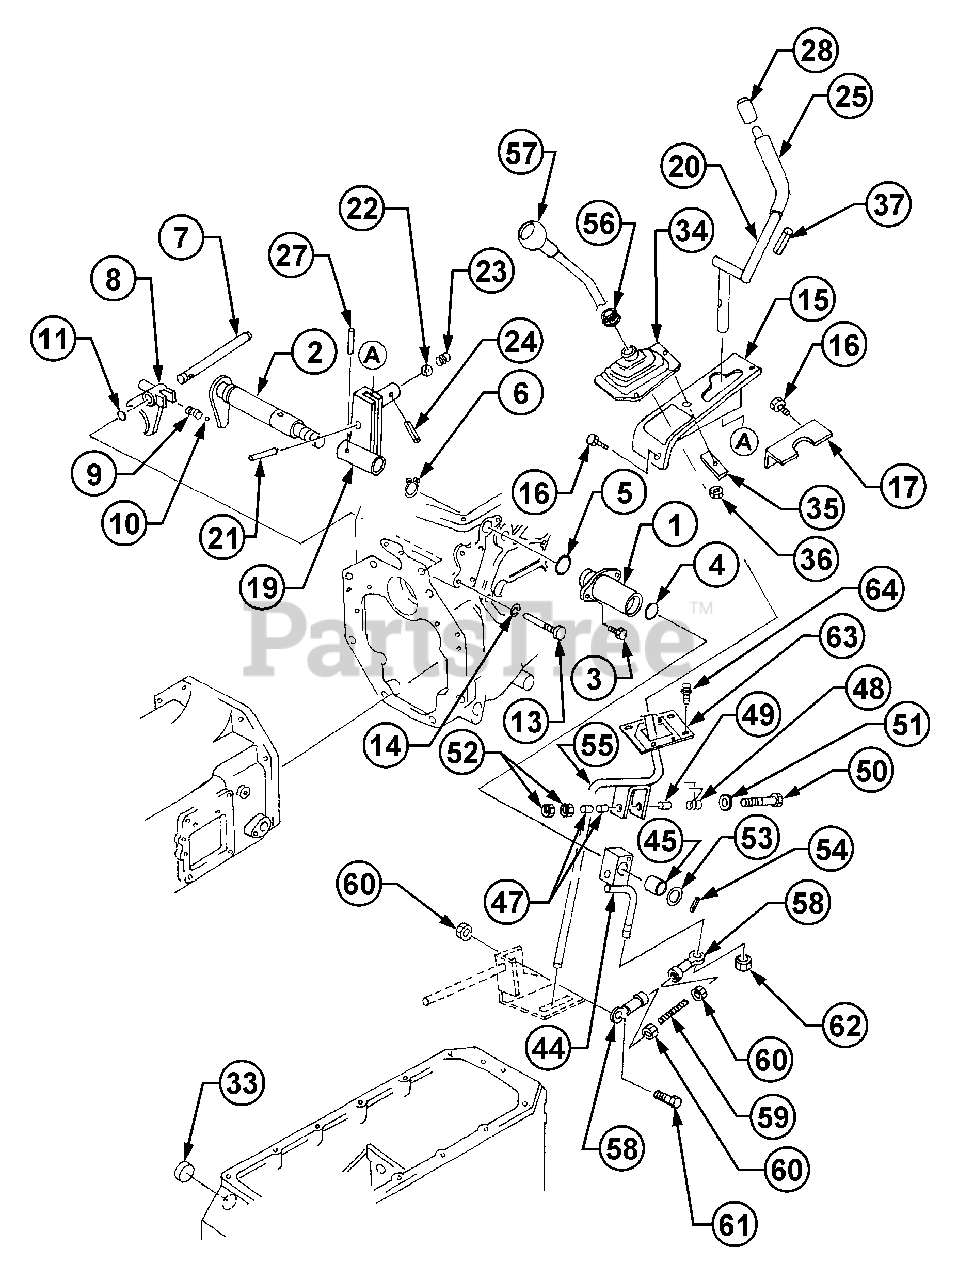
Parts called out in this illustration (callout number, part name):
3	Bolt, w/Washer
11	O-Ring
14	Washer, Spring
19	Bracket, Range
64	Bolt,w/Washer
